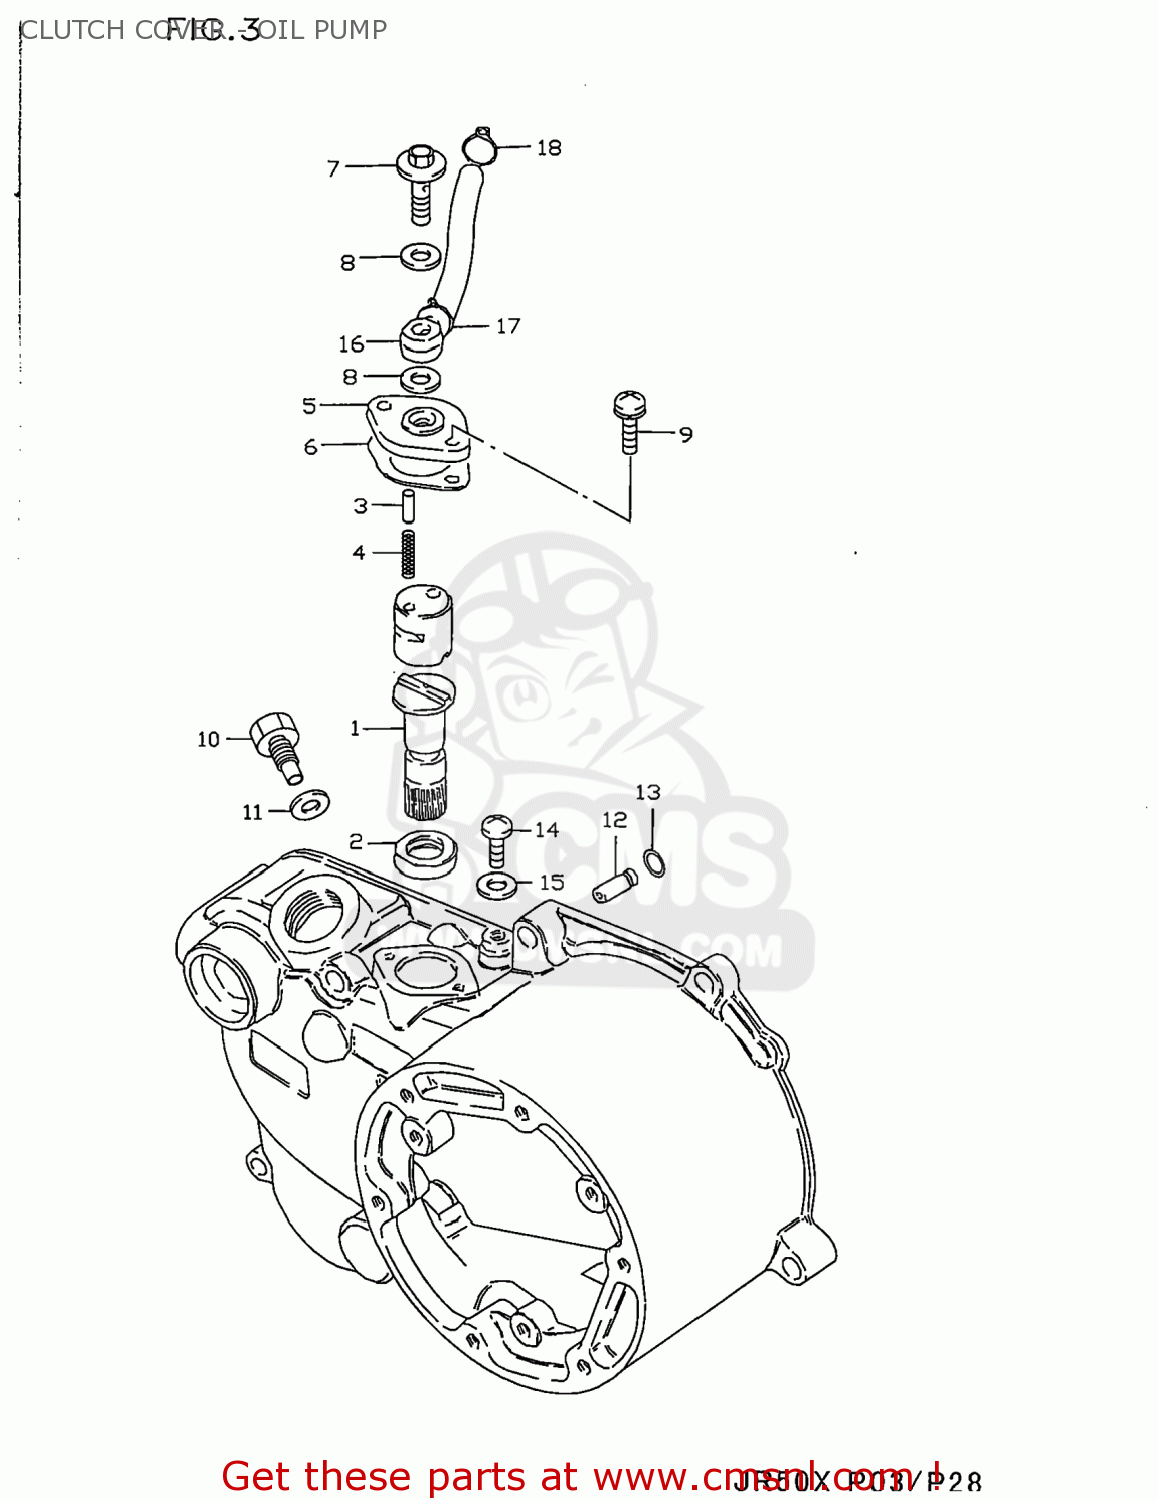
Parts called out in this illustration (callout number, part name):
1	GEAR,OIL PUMP DRIVE
2	SEAL,OIL(12X18.5X3)
3	PIN(2.3X7.5)
4	SPRING
5	CAM,OIL PUMP
6	GASKET,OIL PUMP (NAS)
7	UNION BOLT
8	GASKET(6.2X11X1).2 (NAS)
9	SCREW
10	BOLT(6X10)
11	WASHER
12	VALVE,CRANK CHECK
13	O RING(D:1.05,ID:3.1)
14	SCREW
15	GASKET(5X9.5X1) (NAS)
16	HOSE,INLET
17	CLIP
18	CLIP
